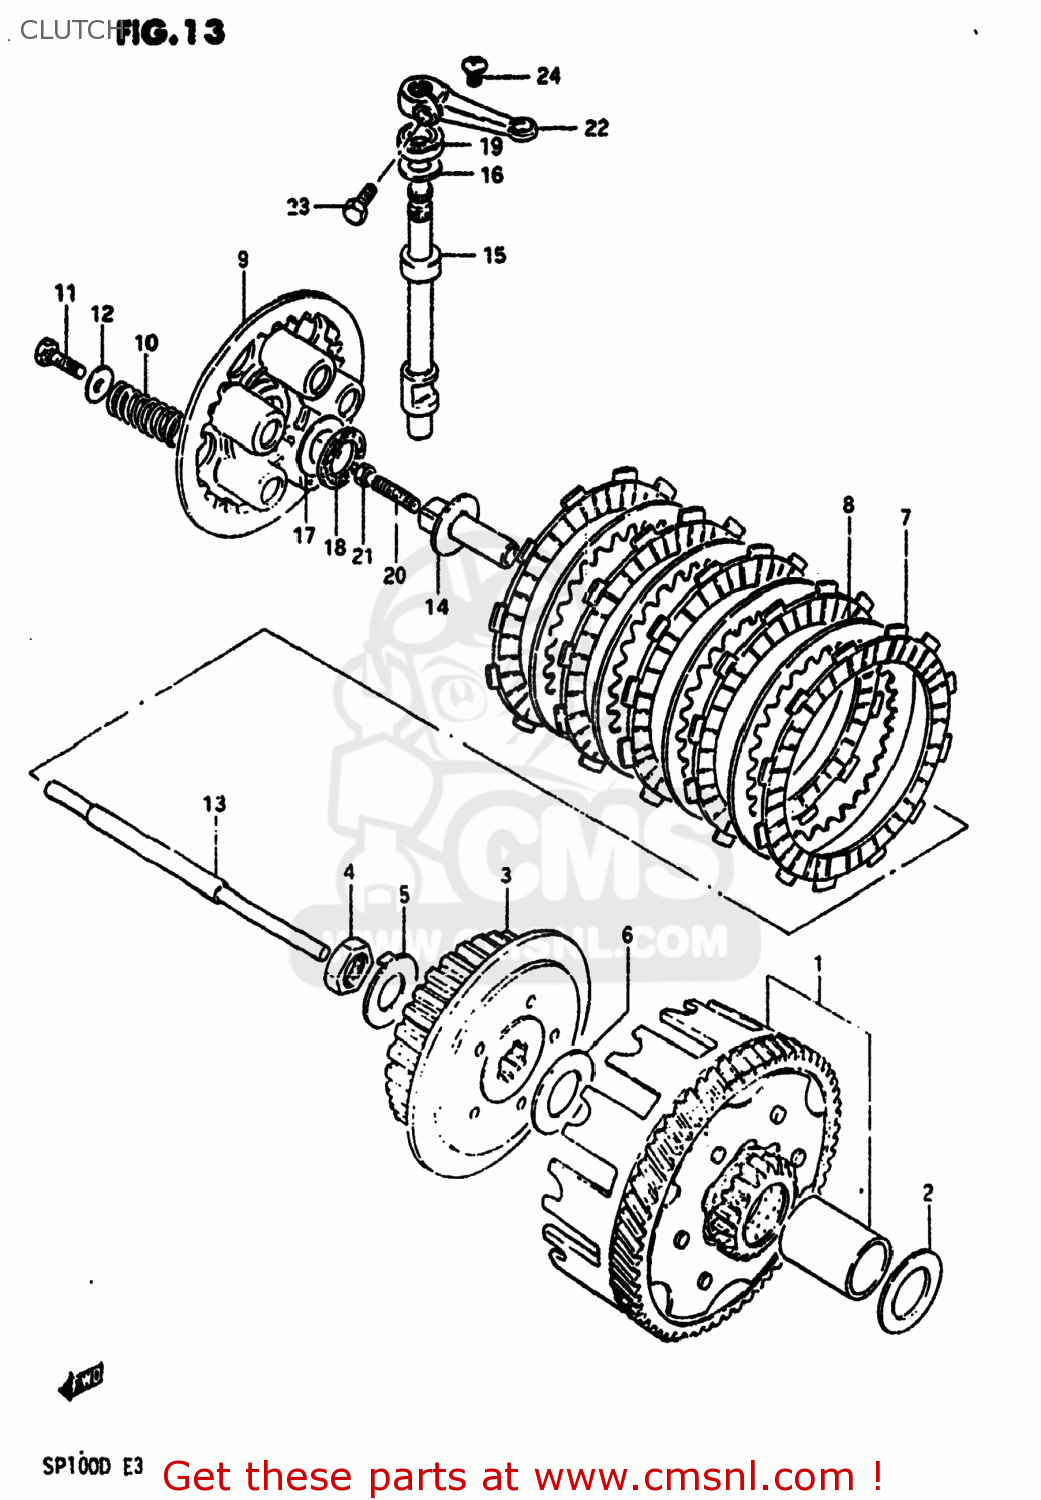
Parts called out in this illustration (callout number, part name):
1	GEAR ASSEMBLY,PRIMARY DRIVE
2	WASHER
3	HUB,CLUTCH SLEEVE
4	NUT
5	WASHER
6	WASHER
7	PLATE,CLUTCH DRIVE
8	PLATE,CLUTCH DRIVEN (NAS)
9	PLATE,CLUTCH PRESSURE
10	SPRING
11	BOLT(5X16)
12	WASHER (5.5X16X1.2)
13	ROD,CLUTCH PUSH
14	PIECE,CLUTCH PUSH
15	CAMSHAFT,CLUTCH RELEASE
16	WASHER,THRUST
17	WASHER
18	BEARING(15X28X2)
19	OIL SEAL
20	SCREW
21	NUT 6MM
22	ARM,CLUTCH RELEASE
23	BOLT, UPPER
24	SCREW
